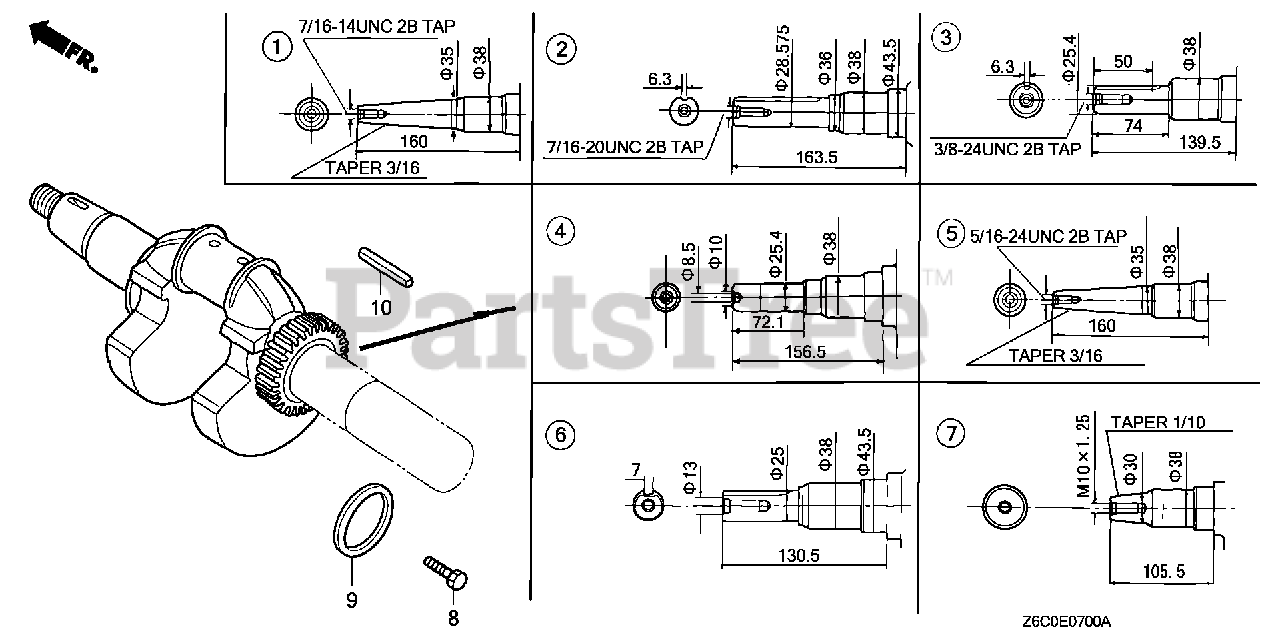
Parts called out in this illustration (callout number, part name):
3	CRANKSHAFT (L=139.5)
9	WASHER, CRANKSHAFT THRUST
10	KEY (6.3X6.3X43)
